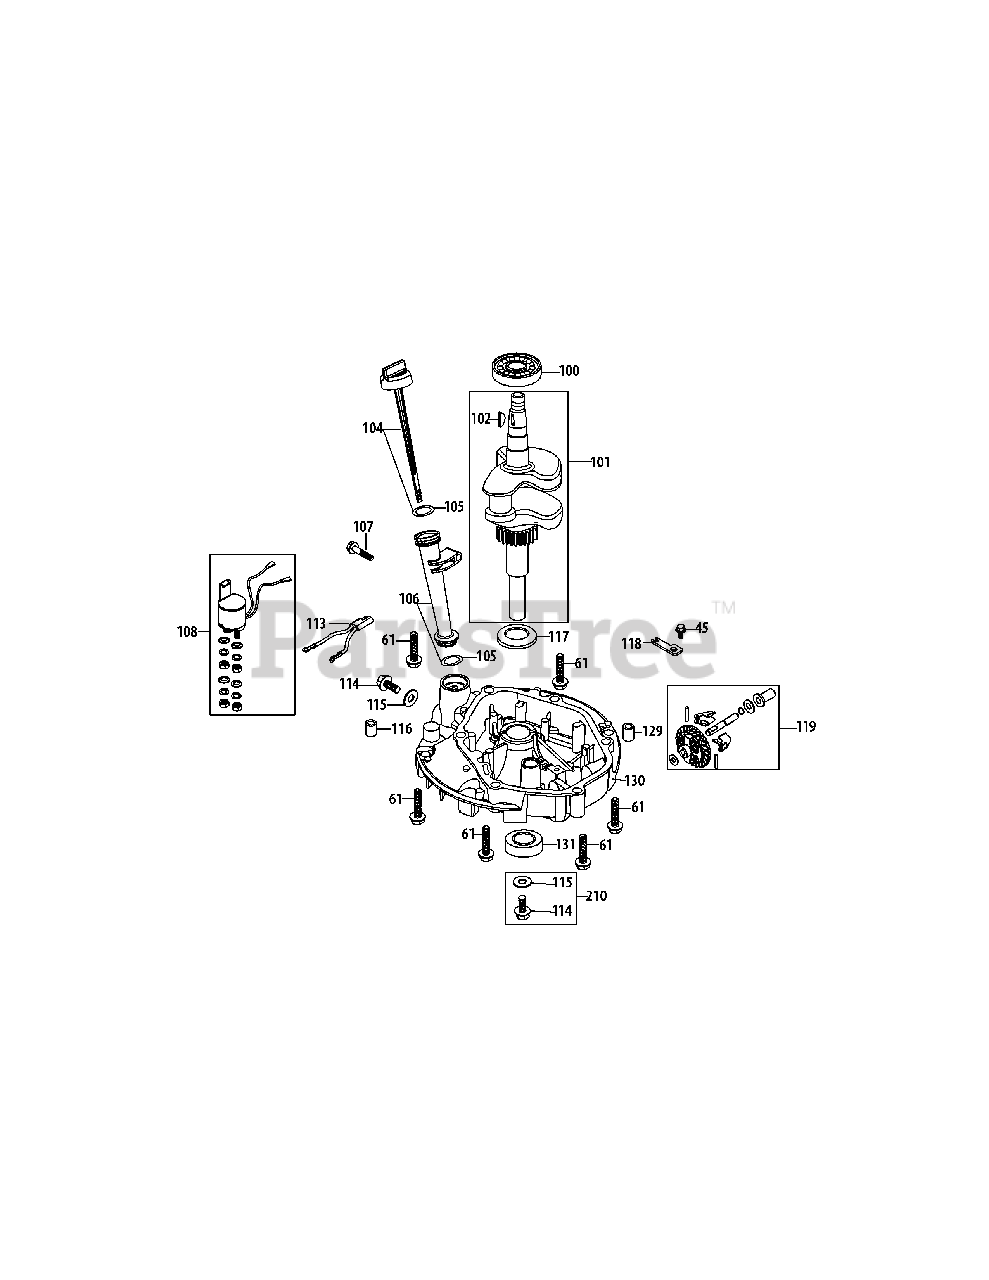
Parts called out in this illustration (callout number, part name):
45	Bolt M6×14
61	Fuel Tank Bolt M8x50
100	Main Bearing
101	Crankshaft Assembly
102	Woodruff Key
104	Dipstick Assembly
105	Oil Fill Tube O-Ring
106	Oil Fill Tube Assemlby
107	Bolt M6×35
108	Starter Relay Assembly
113	Power Connector Harness
114	Oil Drain Plug
115	Oil Drain Plug Washer
116	Crankcase Cover Dowel 9x14
117	Crankshaft Thrust Washer
118	Governor Gear Mounting Plate
119	Governor Gear/Shaft Assembly
129	Crankcase Cover Dowel 7x14
130	Crankcase Cover
131	Lower Crankshaft Seal
210	Oil Drain Plug And Washer Assy
